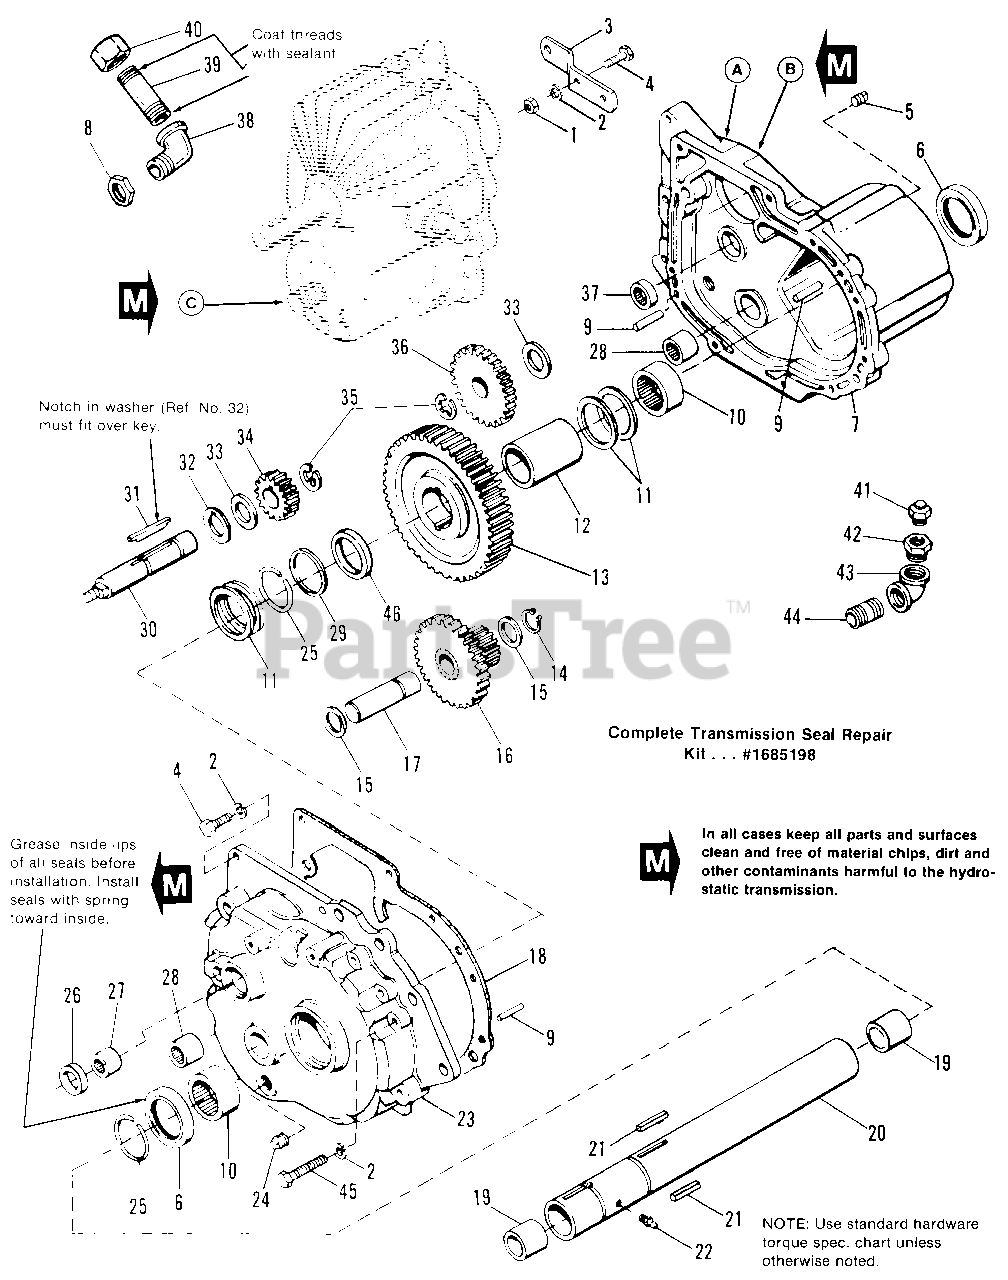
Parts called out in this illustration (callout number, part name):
1	NUT, Hex, Full, 5/16-18
2	LOCKWASHER, 5/16
3	SUPPORT, Spring
4	CAPSCREW, Hex Hd., 5/16-18 x 1
7	CASE ASSY., w/Bearings
8	LOCKNUT, 3/8, Rigid Conduit
9	PIN, Roll, 3/8 x 1
12	SPACER, Axle, L.H.
13	GEAR, Drive
14	RING, Retaining
16	PINION & SHAFT ASSY.
17	SHAFT, Intermediate
20	TUBE ASSY., Axle
21	KEY
22	FITTING, Grease
23	COVER ASSY., Grease Case w/Bearings
25	RING, Retaining
28	BEARING, Needle
30	SHAFT, Brake
35	RING, Retaining
37	BEARING, Needle
38	ELBOW, Street
39	NIPPLE, Pipe
41	VALVE, Refief
42	BUSHING, Pipe
43	ELBOW, Pipe
44	NIPPLE, Pipe
45	CAPSCREW, Hex Head 5/16-18 x 2 G5
46	SPACER, Axle, R.H.
